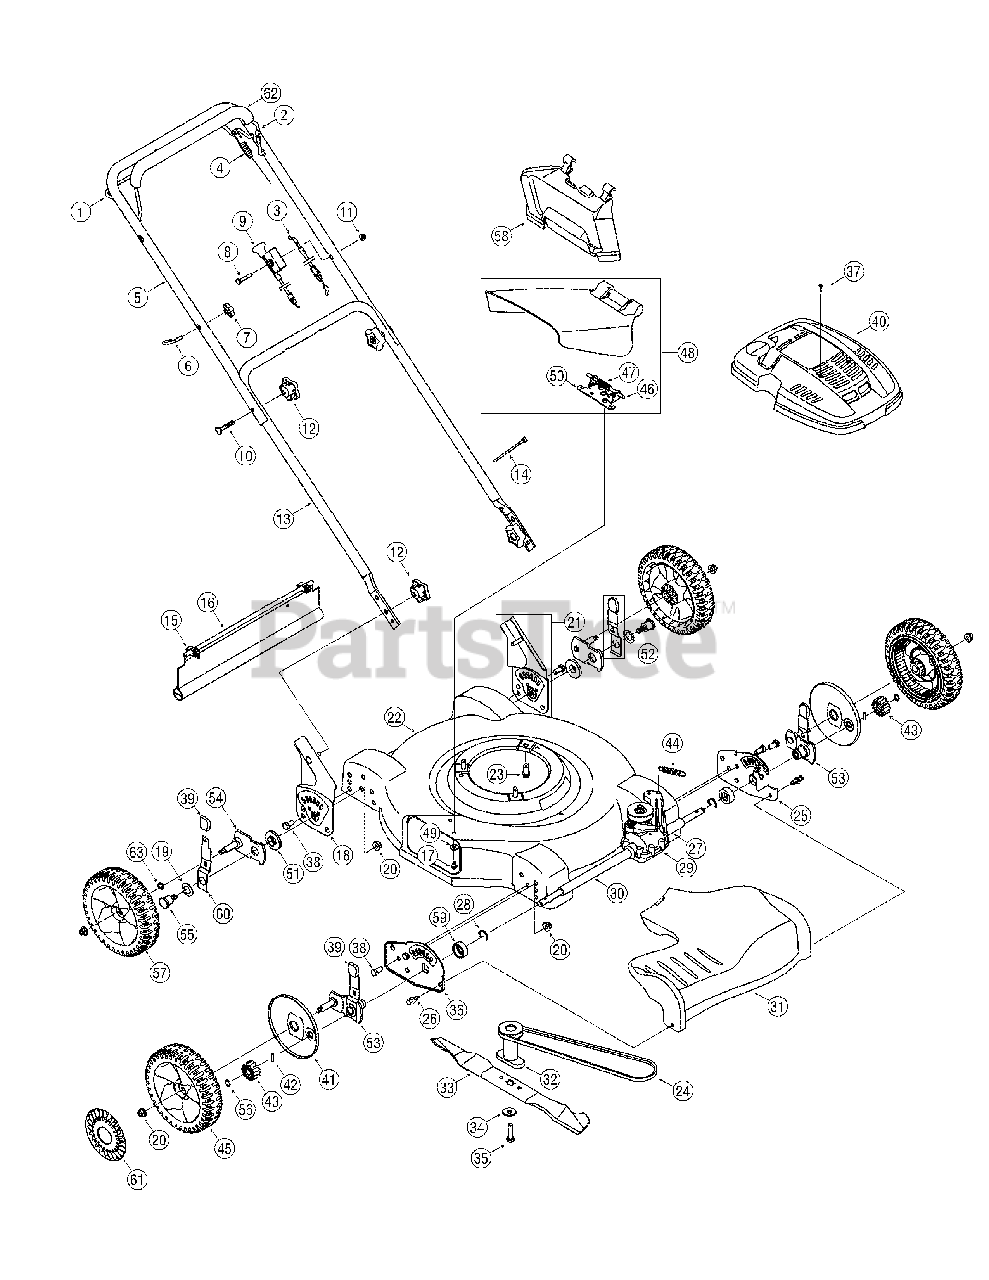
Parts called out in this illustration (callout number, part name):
1	Drive Control
2	Blade Control
3	Blade Control Cable
4	Drive Control Cable
6	Eye Bolt
7	Wing Nut, 1/4-20
8	Hex Screw, 1/4-20 x 1.50
9	Choke Cable
10	Carriage Bolt, 5/16-18 x 2.0
11	Flange Lock Nut, 1/4-20
12	Star Knob
14	Cable Tie
15	Hinge Clip
16	Trail Shield
17	Hex Screw, 1/4-20 x.500
18	Handle Bracket Assy - RH
19	Bell Washer, .760 x 1.25 x.041
20	Lock Nut, 3/8-16
21	Handle Bracket Assembly - LH
23	Hex Washer Scr., 3/8-16 x 1.0
24	V-Belt, 3L x 32.90
25	Forward Height Adj. Plate - LH
26	Rivet
27	Sleeve Spacer, .550 ID x 2.22
28	Retainer Ring
29	Transmission Assy. Comp.
30	Sleeve Spacer, .550 ID x 8.51
31	Transmission Cover
32	Blade Adapter
33	22" Mulching Blade
34	Washer, Bell, .396 x 1.140 x .095
35	Hex Cap Screw, 3/8-24 x 1.5
36	Forward Hght. Adj. Plate - RH
37	Machine Screw, M4X.7
38	Hex Cap Screw, 3/8-16 x.75
39	Adjustment Knob
40	Engine Shroud (Yellow)
40	Engine Shroud (Black)
41	Wheel Dust Cover
43	Spur Gear 14T - RH
43	Spur Gear 14T - LH
44	Ext. Spring, .47 OD x 2.50
45	Front Wheel, 8 x 2.125
46	Hinge Pin
47	Torsion Spring
48	Side Discharge Assembly
49	Bell Washer, .265 ID x.75 OD
50	Deflector Chute Adapter
51	Height Adjustment Bearing
52	Rear Hgt. Adj. Lever Assembly
53	Front Lever Assembly - RH
53	Front Lever Assembly - LH
54	Rear Pivot Arm Assembly
55	Shoulder Screw, 3/8-16
56	Snap Ring.500
57	Rear Wheel, 8 x 2.125
58	Mulching Baffle
59	Bearing Support Spacer
60	Spring Lever
61	Hub Cap
62	Deluxe Bail Cover
63	Washer, Wave, .510 x .750 x .017
